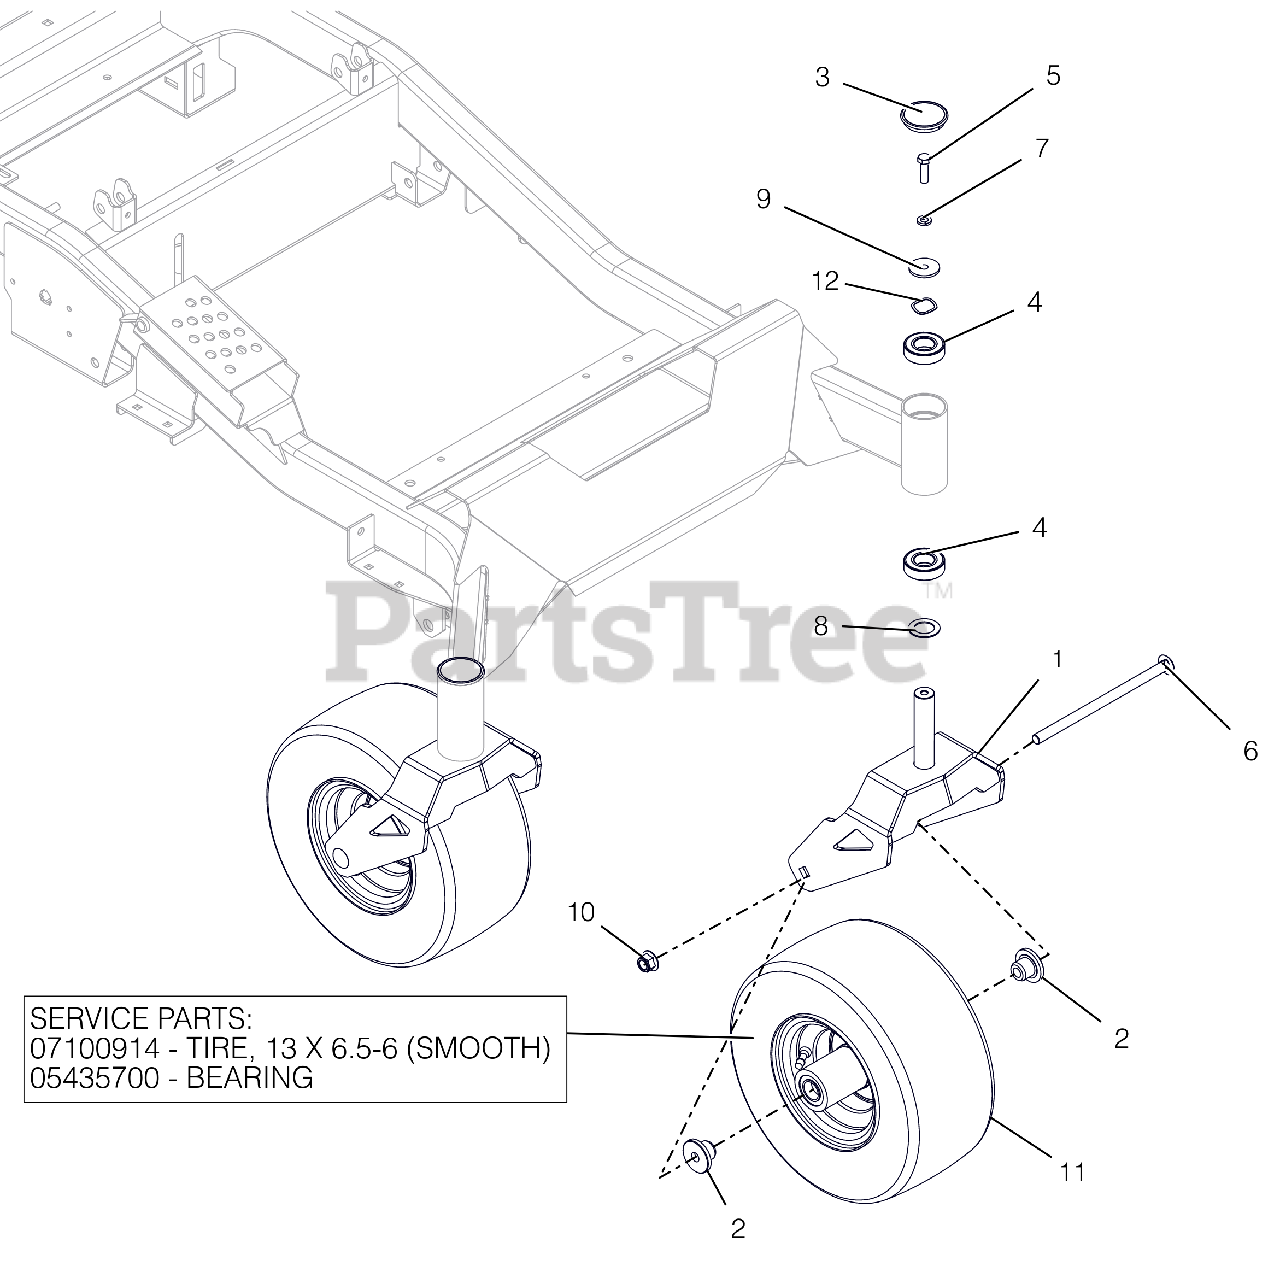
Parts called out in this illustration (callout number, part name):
1	WLDMT, HD CASTER FORK
2	SPACER, FRONT WHEEL
3	CAP, DUST
4	BRG,BALL 1.00X2.00X.563(1641)
5	@BLT-HEX .38-16X1.25 GR5 YWZC
6	BLT-RDHDSQNK .50-13X9.00 G5 Y
7	WSHR-LK .375X.115 HVY YWZC
8	WSHR-HRD-THRS 1.007X1.542X.062
9	WSHR-FL-STL .380X1.50X.125YWZC
10	@NUT-LK-NYL-FLG .50-13 YWZC
11	ASM, WHL/TIRE 13X6.50-6
11	TIRE, 13X6.50-6 SMOOTH
11	BRG, 25MM ID X 52MM OD X 15MM
12	WSHR-WAVE 1.0X1.25X.028 .145FH
